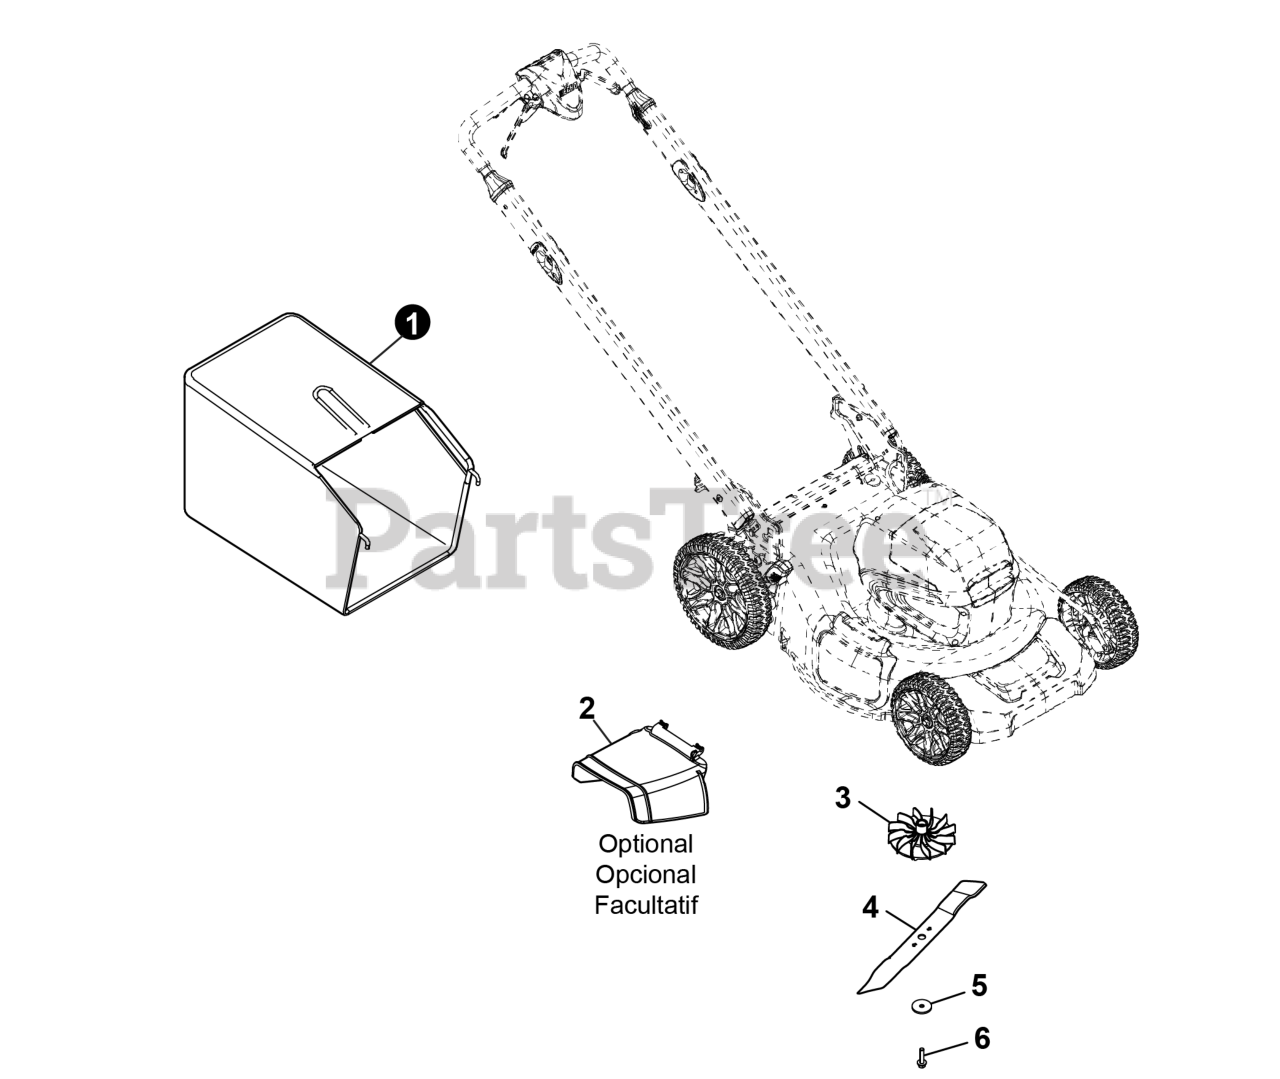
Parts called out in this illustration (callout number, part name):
1	BAG ASSY, GRASS
2	CHUTE, SIDE DISCHARGE
6	BOLT, BLADE
